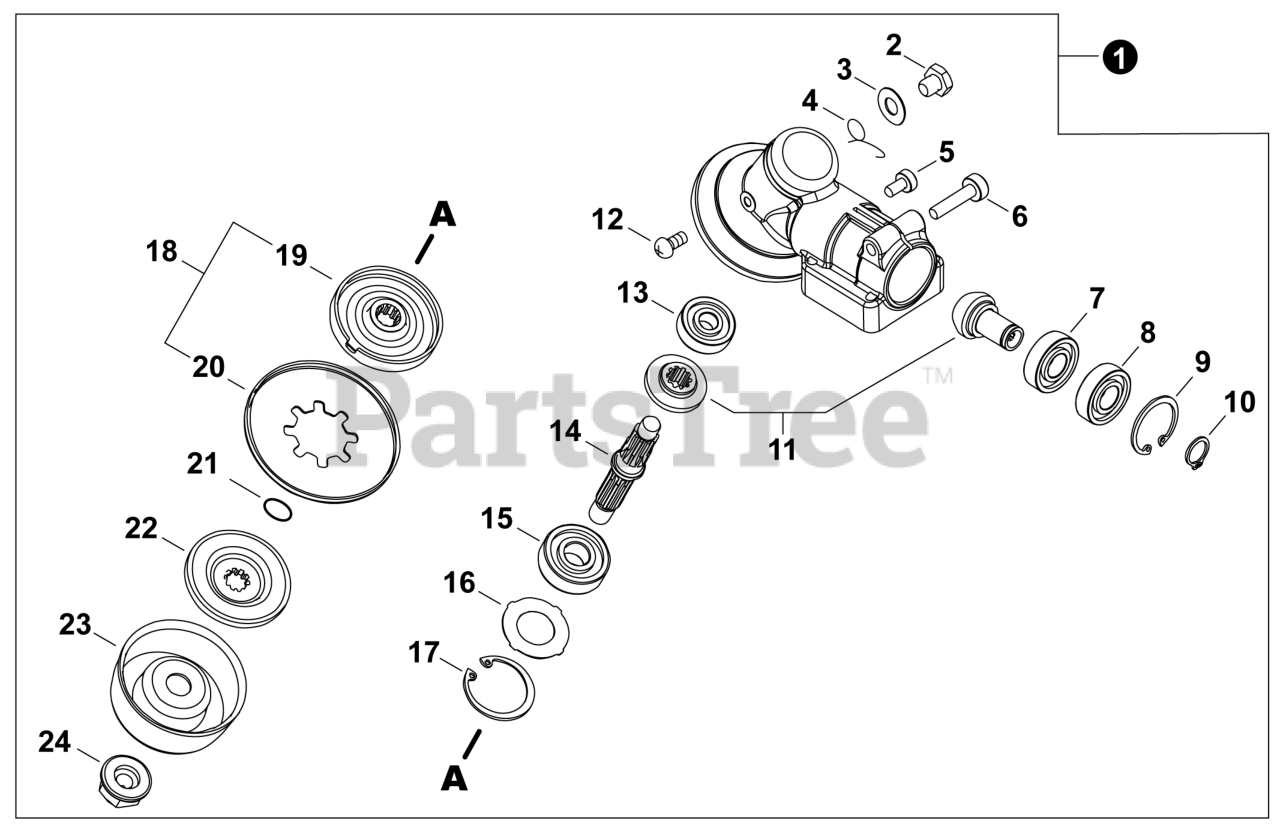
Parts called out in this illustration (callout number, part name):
1	CASE, GEAR
2	BOLT M8×8
3	WASHER 8.5×18×0.8T
4	SPRING, TORSION
5	BOLT, TORX 5×10
6	BOLT, TORX 6×30
7	BEARING, BALL 6001
8	BEARING, BALL 6001Z
9	RING, SNAP 28
10	RING, SNAP 12
11	GEAR SET
12	SCREW 4×6
13	BEARING, BALL 629
14	SHAFT, GEAR
15	BEARING, BALL 6201
17	RING, SNAP Ø32
18	RETAINER, BLADE
19	PLATE, ADAPTOR
20	PLATE, ADAPTOR - LOWER
21	O-RING 12 MM
22	PLATE, ADAPTOR - LOWER
24	NUT, LOCK 10 - NYLON INSERT
